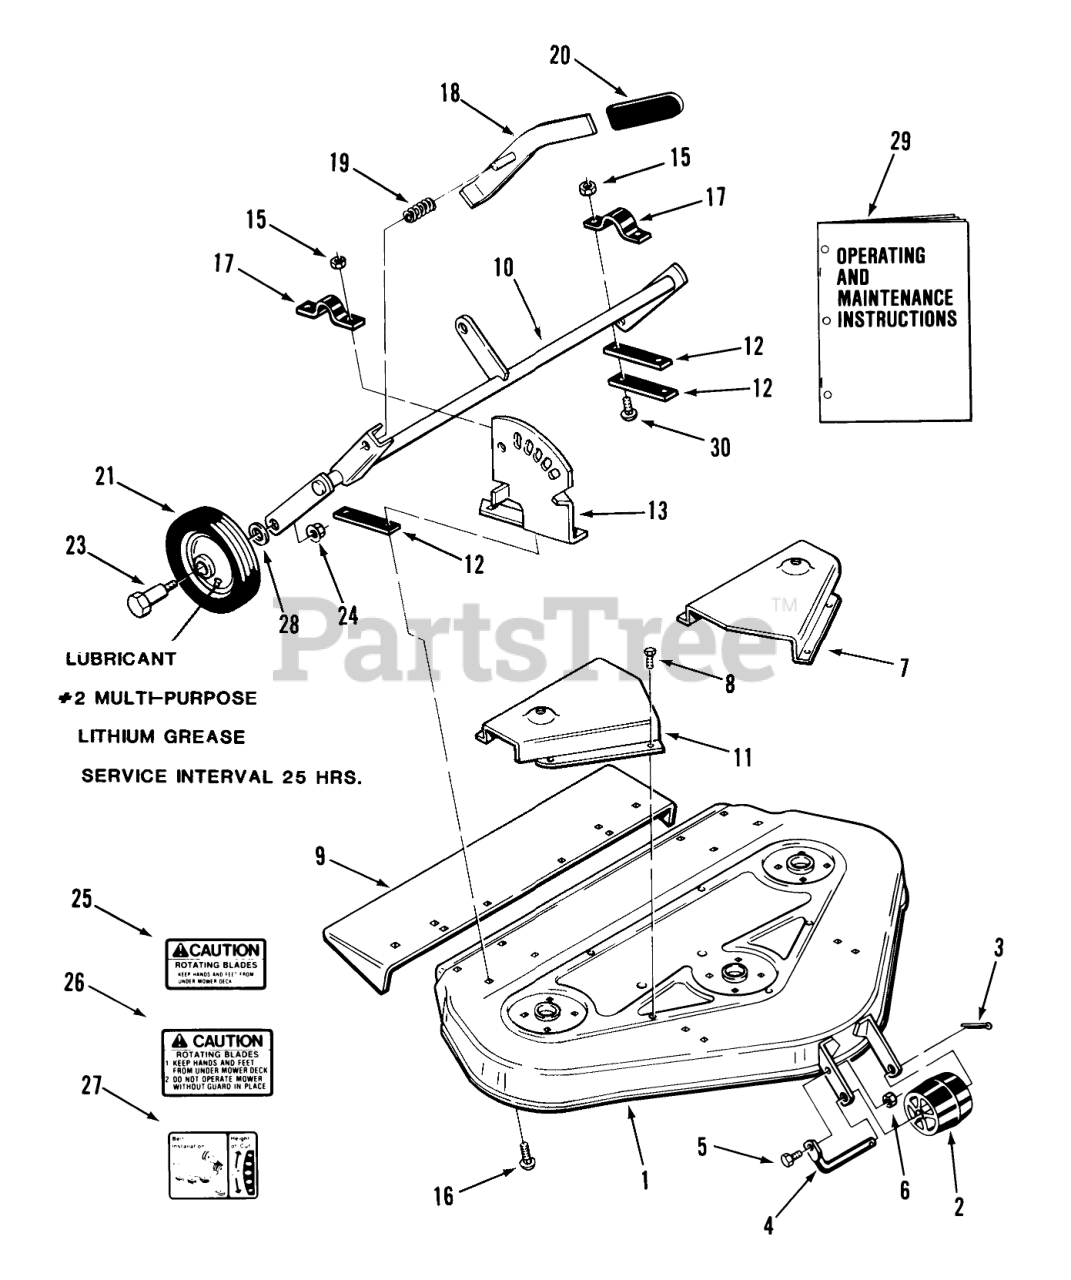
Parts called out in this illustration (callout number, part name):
4	ROLLER-SHAFT
17	CLAMP
19	SPRING-COMPRESSION
21	WHEEL
23	BOLT-SHOULDER
27	DECAL-HEIGHT & BELT
28	WASHER
29	Operating and Maintenance Instructions
